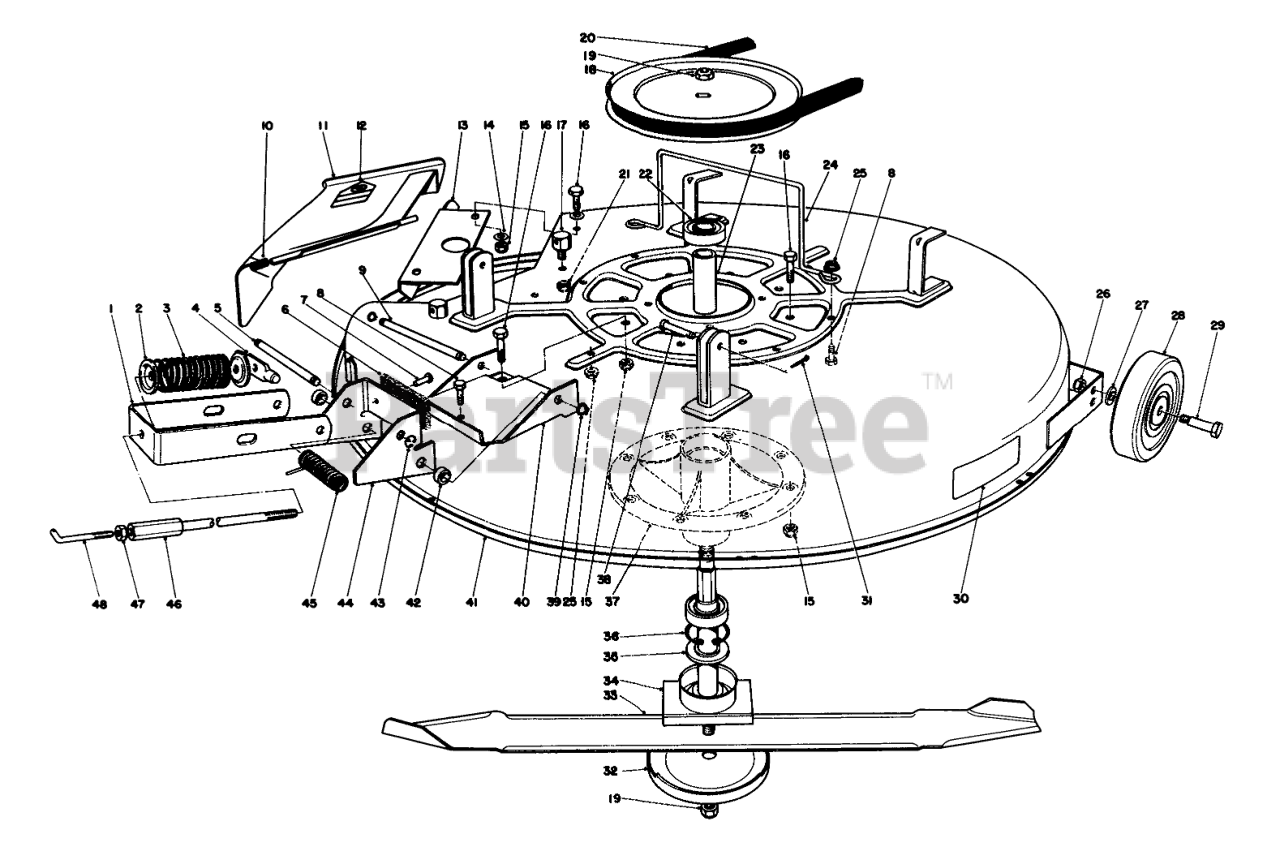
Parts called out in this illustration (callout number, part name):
1	Bracket-Engagement
2	RETAINER-SPR. TOP
3	SPRING-COMPRESSION
4	SHAFT-DECK ADJ.
5	Pin-Clevis
6	BRAKE PAD
7	RIVET .187 X 7/16 BRASS
8	SCREW-HH
9	CLEVIS PIN
10	SPRING
11	Deflector Assembly (Incl. Ref. #12)
12	DECAL-DANGER
13	Baffle Deck
14	WASHER-PLAIN
15	NUT-LOCK, NI
16	SCREW-HH
17	POST-PIVOT
18	PULLEY
20	V-BELT, DECK
21	NUT-LOCK, SIDE
22	BEARING-BALL
23	Spacer-Bearing
24	Guide-Belt
25	NUT-LOCK, HHF
26	NUT-LOCK, NI
27	WASHER-FLAT
28	DECK WHEEL
29	BOLT-WHEEL
30	DECK DECAL
31	PIN-COTTER
32	Cup
33	Blade
34	SPINDLE SHAFT WA
35	SPACER-SPINDLE
36	RING-RETAINING
37	SPINDLE
38	PIN-CLEVIS
39	RING-RETAINING
40	DECK ENGAGE CHANNEL R
41	Cutter Deck
42	DECK BRAKE SPACER
43	E-RING
44	Support Deck Brake Assembly (Incl. Ref. #6 & 7)
45	SPRING
46	ADJ HUB WA
47	NUT-JAM
48	ADJ. ROD
